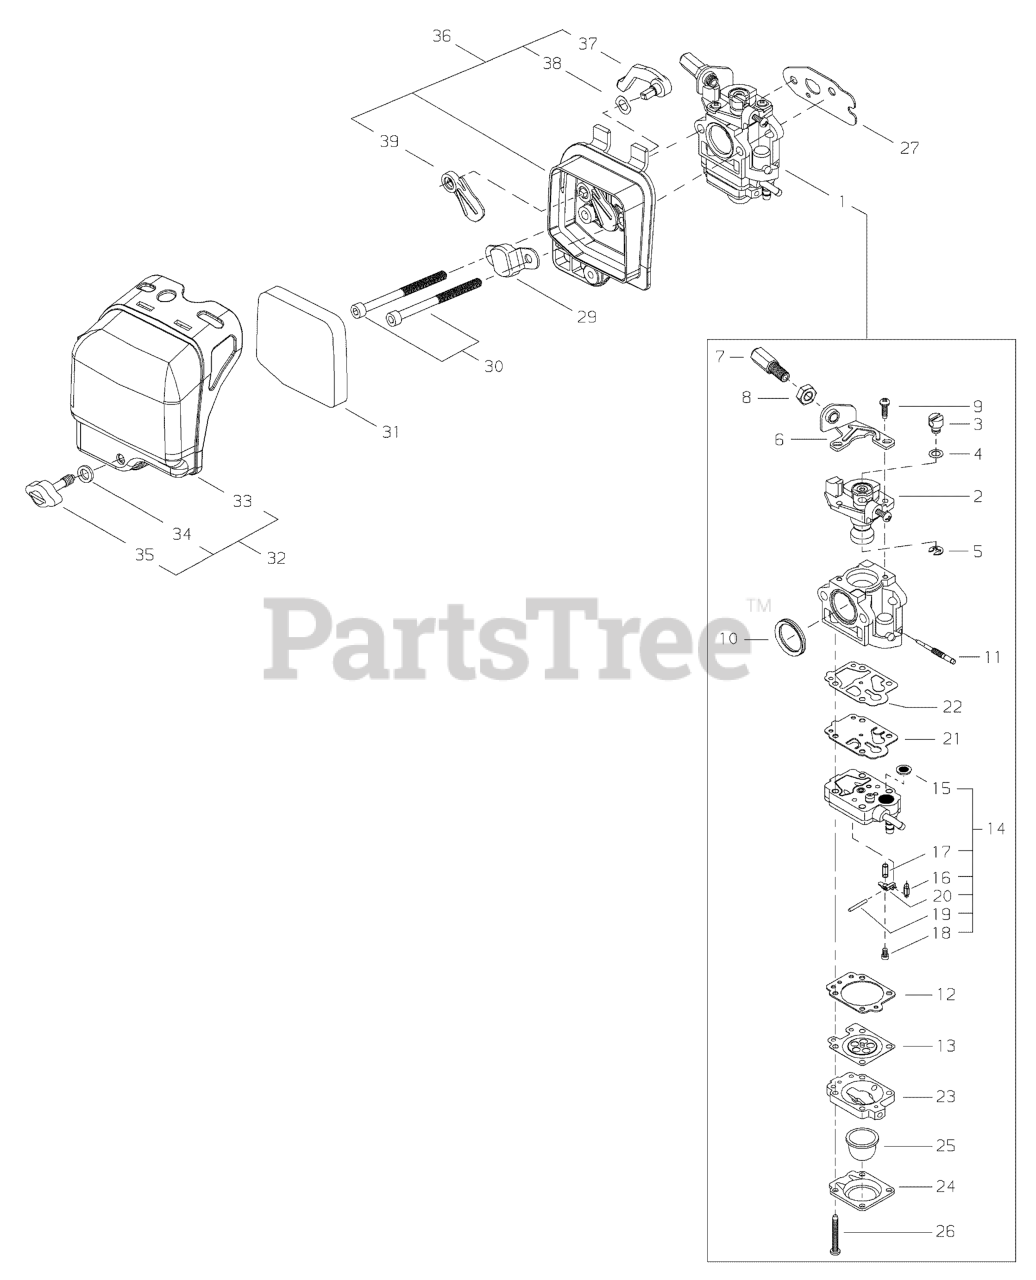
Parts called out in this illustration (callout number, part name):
1	CARBURETOR
2	THROTTLE VALVE ASSY
3	SWIVEL
4	WASHER
5	RING, RETAINING
6	BRACKET, CABLE
7	NUT, CABLE ADJUST
8	NUT
9	SCREW
10	SEAL
11	NEEDLE - HIGH SPEED
12	GASKET, METERING
13	DIAPHRAGM, METERING
14	PUMP BODY ASSY
15	STRAINER
16	VALVE, INLET NEEDLE
17	SPRING, METERING LEVER
18	SCREW, METERING LEVER PIN
19	PIN, METERING LEVER
20	LEVER, METERING
21	DIAPHRAGM, PUMP
22	GASKET, PUMP
23	BASE, PURGE
24	RETAINER, PURGE BULB
25	BULB, PURGE
26	SCREW, PUMP COVER
27	GASKET, INTAKE
29	PLATE, PREVENT
30	SCREW - 5X60
31	FILTER, AIR
32	AIR FILTER COVER ASSY
33	COVER, AIR FILTER
34	WASHER - VINYL
35	THUMBSCREW
36	AIR FILTER CASE ASSY
37	LEVER, CHOKE
38	WASHER - SPRING
39	PLATE, CHOKE
